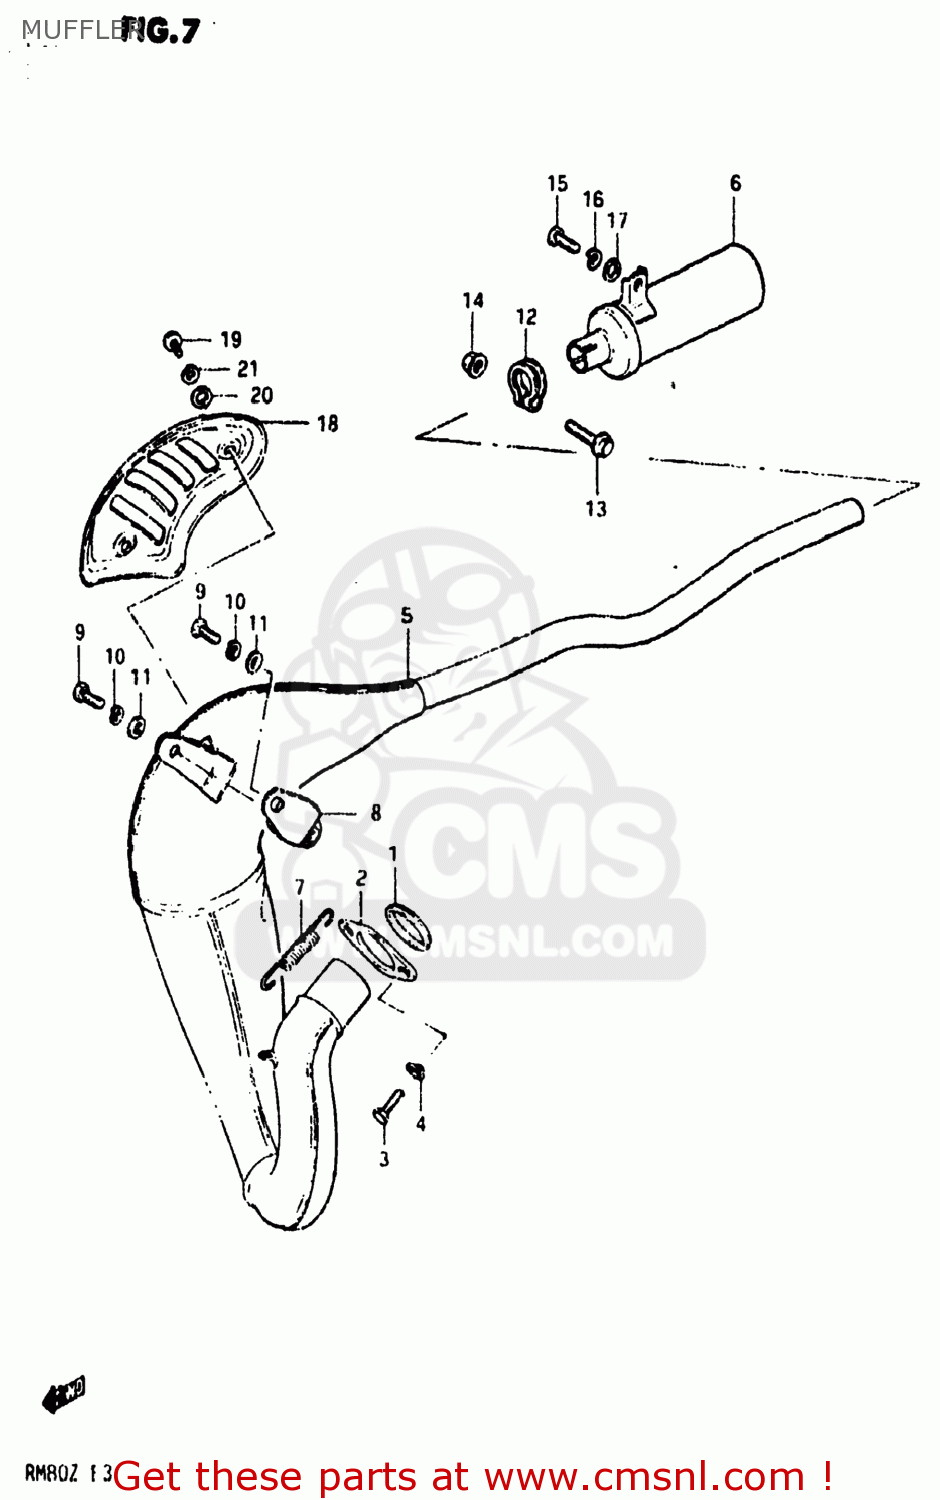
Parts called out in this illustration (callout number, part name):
1	GASKET,EXHAUST PIPE (NAS)
2	CLAMP,EXHAUST PIPE
3	BOLT, UPPER
4	LOCK WASHER
5	BODY,MUFFLER
6	BODY,MUFFLER
7	SPRING
8	DAMPER,MUFFLER SUPPORT
9	BOLT
10	LOCK WASHER
11	WASHER
12	CLAMP,EXHAUST
13	BOLT
14	NUT 6MM
15	BOLT
16	LOCK WASHER
17	WASHER
18	COVER,MUFFLER
19	SCREW
20	WASHER
21	LOCK WASHER
